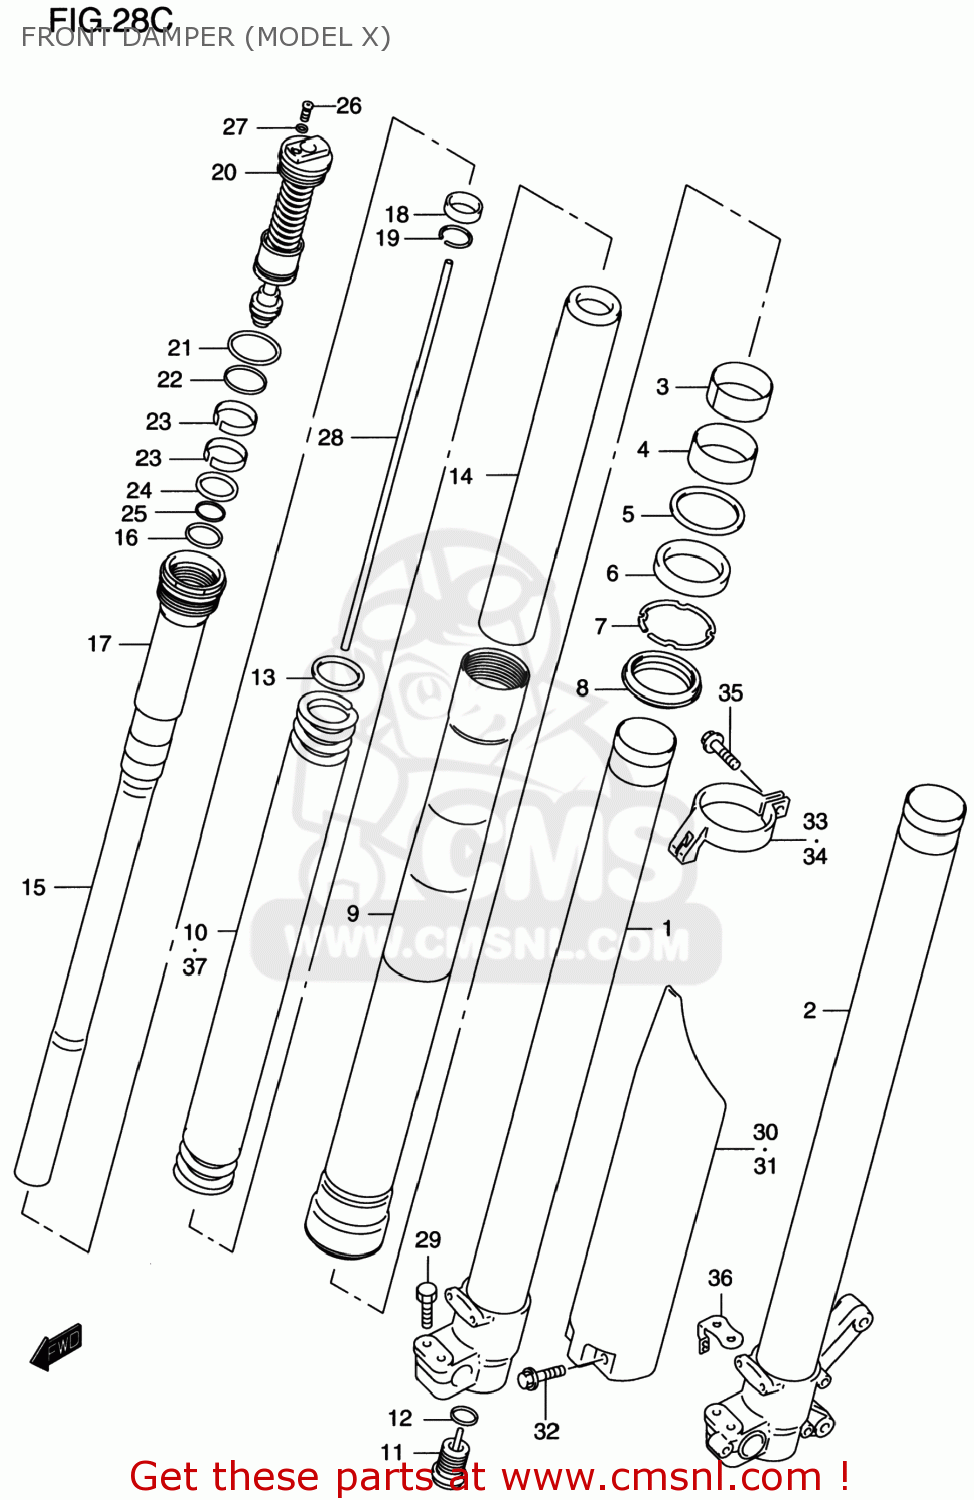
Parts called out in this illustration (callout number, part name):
1	TUBE,INNER,RIGHT
2	TUBE,INNER,L
3	BUSH,SLIDE
4	BUSH,GUIDE
5	SPACER,SEAL
6	SEAL,OIL
7	RING,STOPPER
8	SEAL,DUST
9	TUBE,OUTER
10	SPRING,FR(K=0.40)
11	BOLT,CTR
12	O RING
13	STOPPER,SPRING
14	COLLAR,SPRING
15	DAMPER,CARTRIDGE
16	O-RING
17	TANK,SUB
18	VALVE,OIL LOCK
19	RING,STOPPER
20	BOLT,FORK
21	O RING
22	O RING
23	BUSH,FORK BOLT SLIDE
24	O RING
25	O RING,LWR
26	BOLT,PLUG
27	O RING,PLUG
28	ROD,PUSH
29	BOLT,HANDLE HOLDER(8X35)
30	PROTECTOR FORK,R
31	PROTECTOR,FORK,L
32	BOLT,PROTECTOR(6X10)
33	GUIDE,PROTECTOR,R
34	GUIDE,PROTECTOR,L
35	BOLT
36	STOPPER,BRAKE HOSE,L
37	SPRING,FR(K=0.38)
